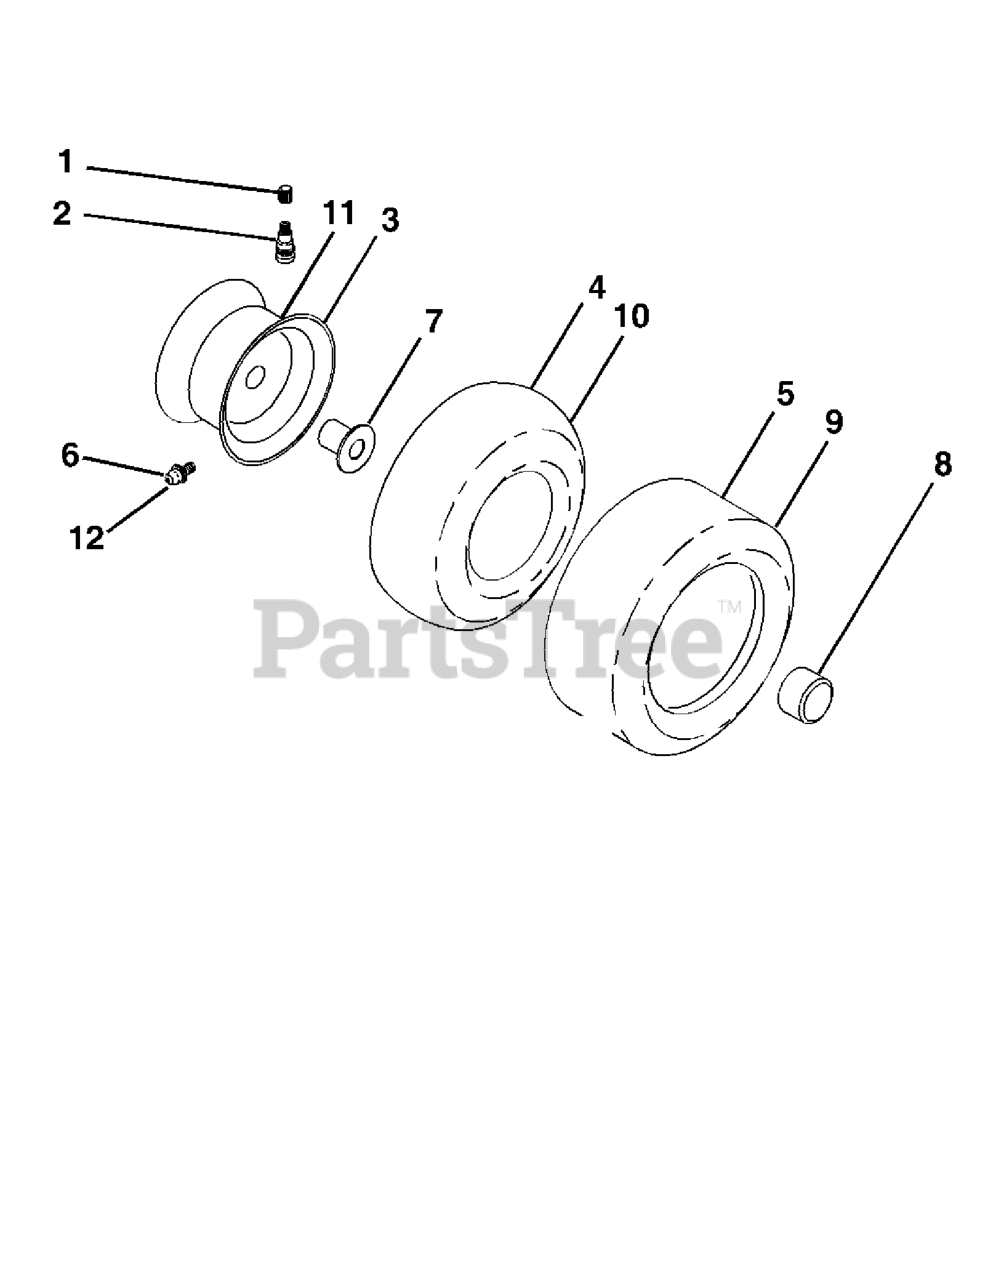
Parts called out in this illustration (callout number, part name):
1	VALVE CAP
2	VALVE STEM LT
3	RIM ASSEMBLY, FRONT
4	TUBE.16X6.5/7.5-8
5	TIRE HEAVY DUTY
6	FITTING LT
7	BEARING T
8	CAP, AXLE BLK
9	TIRE HEAVY DUTY
10	TUBE.23X9.5-12
11	RIM.ASM.12X7.REAR.SILVER
12	ZERK FITTING M
